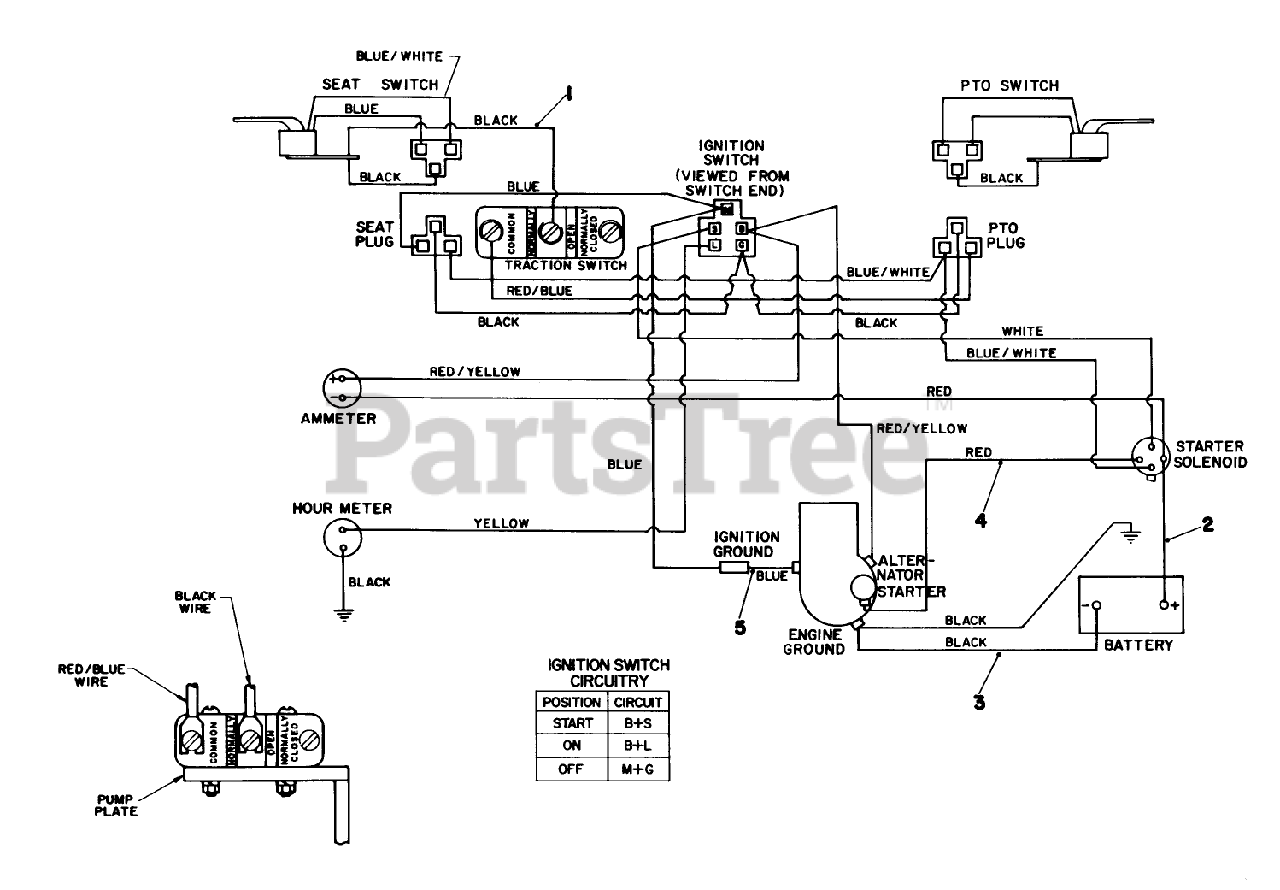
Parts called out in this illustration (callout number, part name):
1	WIRE HARNESS
2	BATT/SOLENOID WIRE
3	BATTERY GROUND WIRE
4	SOLENOID TO START WIR
5	ENGINE GROUND WIRE
